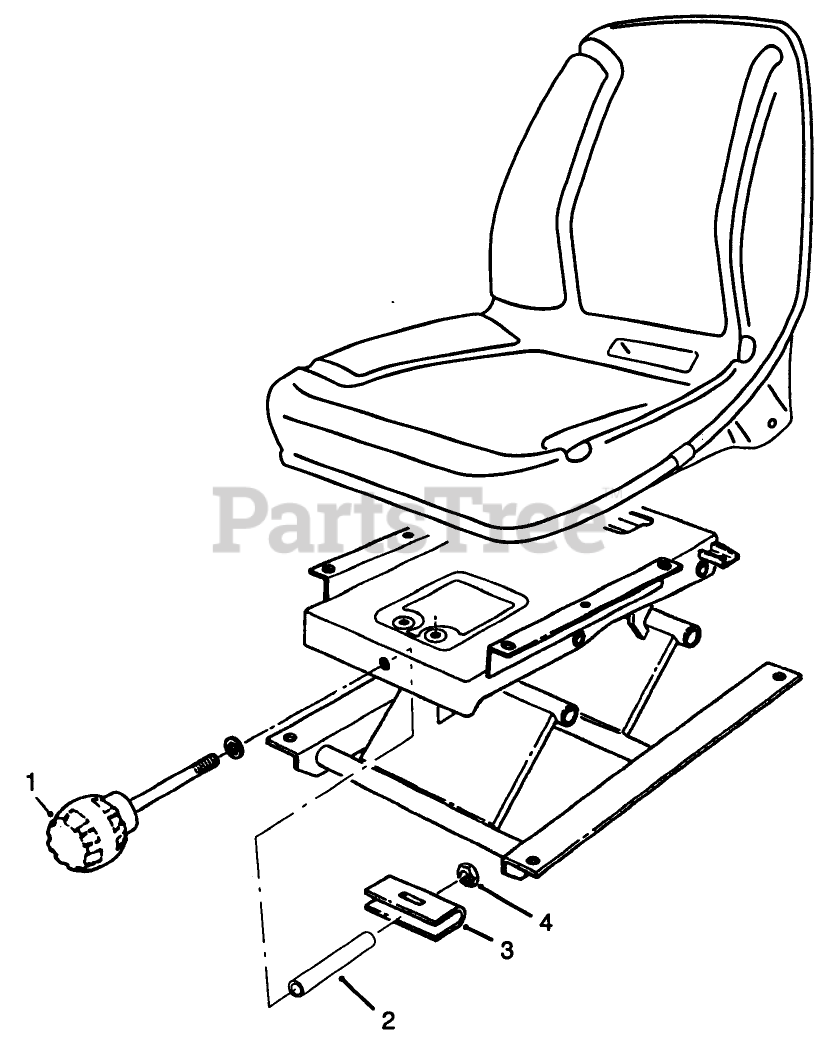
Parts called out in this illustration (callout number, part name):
1	KNOB-ADJUSTER, TENSION
2	PIVOT-IDLER SPACER
3	Hanger-Spring
4	NUT-LOCK, SIDE
